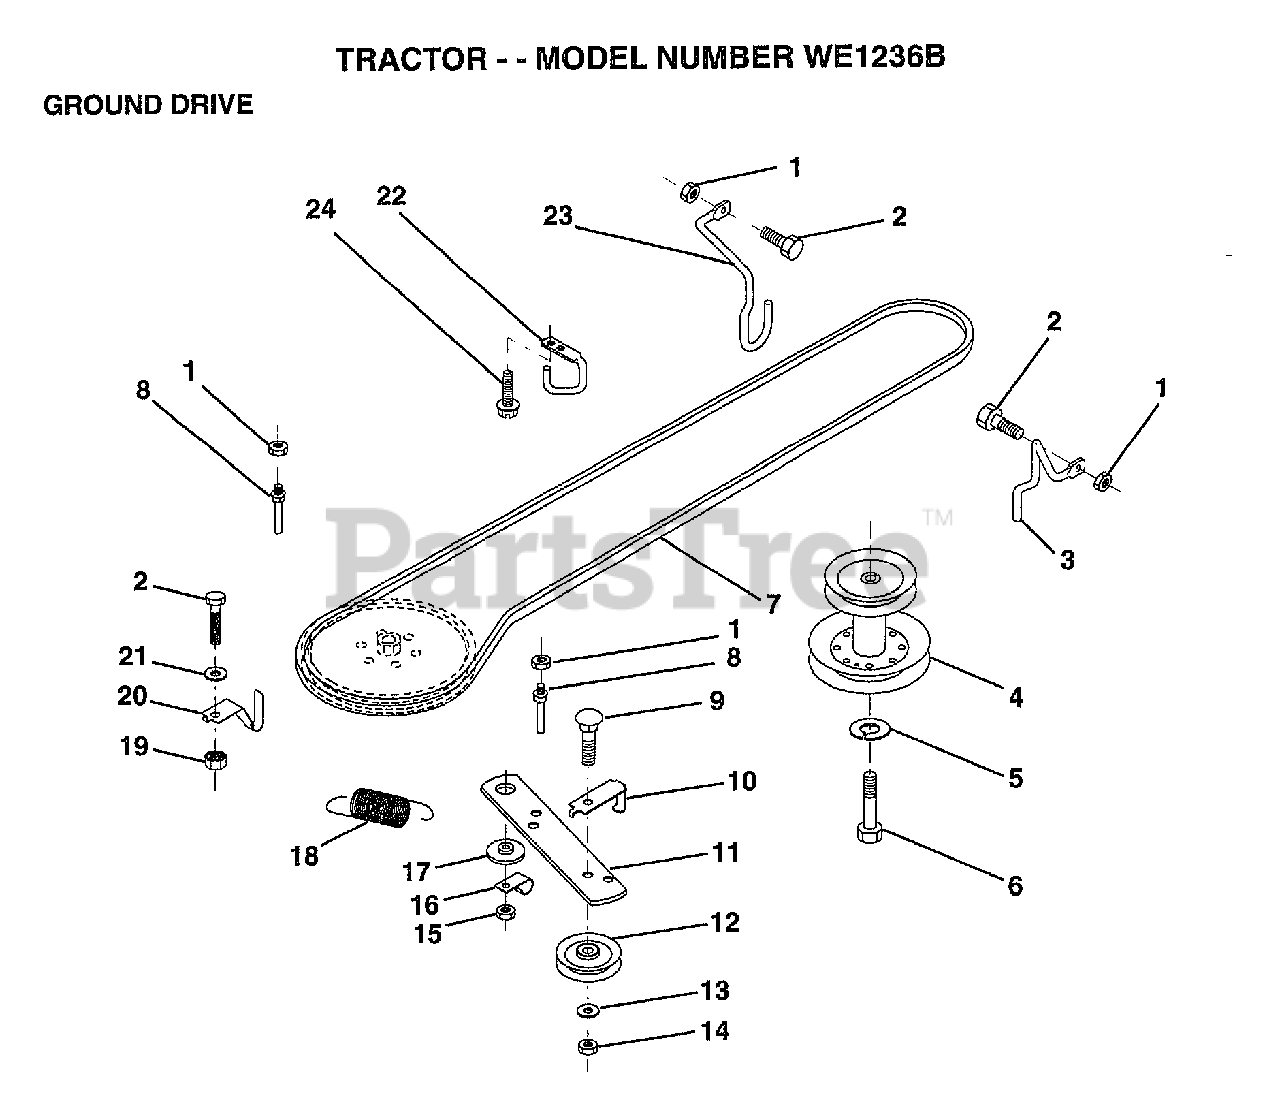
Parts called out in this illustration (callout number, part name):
2	BOLT
3	KEEPER RH
4	PULLEY.ENGINE.LR
5	LOCKWASHER
6	HEX BOLT
7	BELT
8	"KEEPER,DRIVE BELT"
9	BOLT
10	"KEEP,IDLER DR BEL"
11	ARM IDLER CLUT GD
12	PULLEY.IDLER.FLAT
13	WASHER
14	LOCKNUT
16	"CLIP,INSULATOR"
17	SPACER RETAINER
20	KEEPER.BELT.T/A
21	WASHER
22	"KEEPER,FRA DR BEL"
23	KEEPER MOWER LH
24	SCREW
